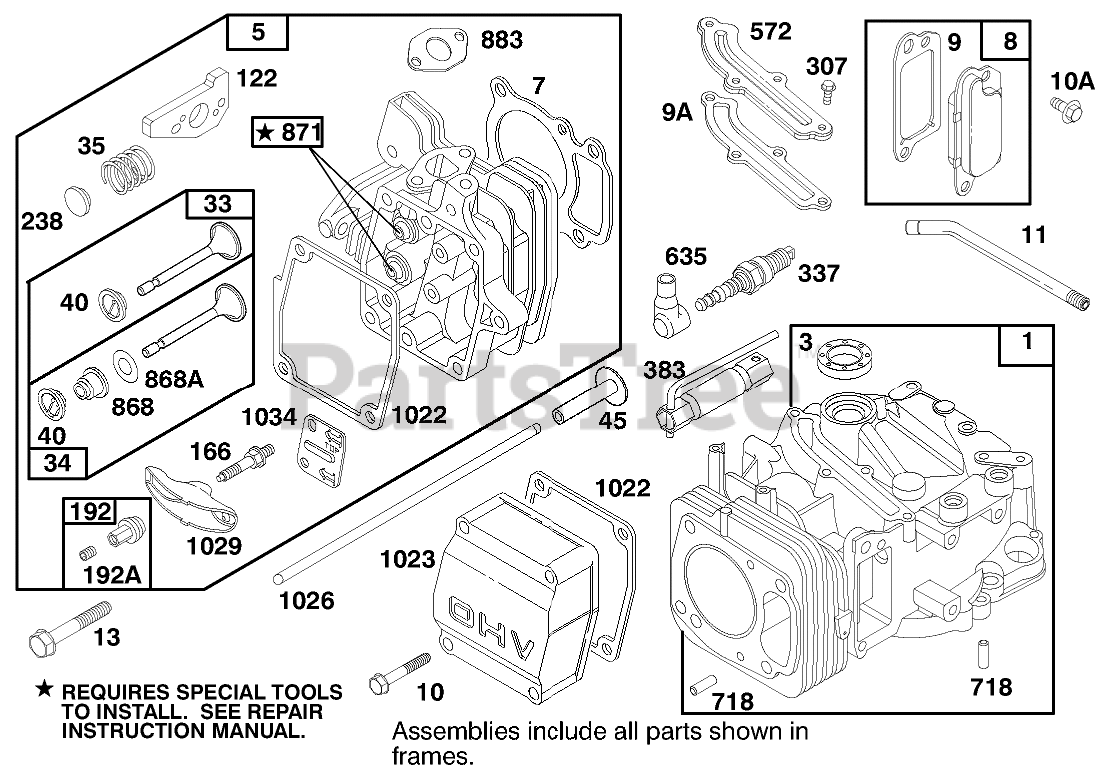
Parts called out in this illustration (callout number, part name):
1	CYLINDER ASSEMBLY
3	SEAL - OIL
5	CYLINDER HEAD
7	CYLINDER HEAD GASKET
8	Breather Assy
9	BREATHER GASKET
9A	GASKET-BREATHER
10	HEX HEAD SCREW
10A	HEX HEAD SCREW
11	TUBE - BREATHER
13	CYLINDER HEAD SCREW
33	EXHAUST VALVE
34	INTAKE VALVE
35	VALVE SPRING
40	SPRING RETAINER
45	VALVE TAPPET
122	ADAPTER ASSEMBLY
166	ROCKER ARM STUD
192	NUT - HEX SPECIAL
192A	SCREW SET
238	VALVE CAP
307	SCREW - SEM
337	PLUG-SPARK
383	WRENCH-SPARK PLUG
572	BAFFLE - CYCLINDER
635	SPARK PLUG ELBOW
718	DOWEL - SLEEVE
868	SealAssy-Valve
868A	Seal-Valve
883	EXHAUST GASKET
1022	ROCKER COVER GASKET
1023	COVER - VALVE
1026	PUSH ROD
1029	ROCKER ARM
1034	PUSH ROD GUIDE
